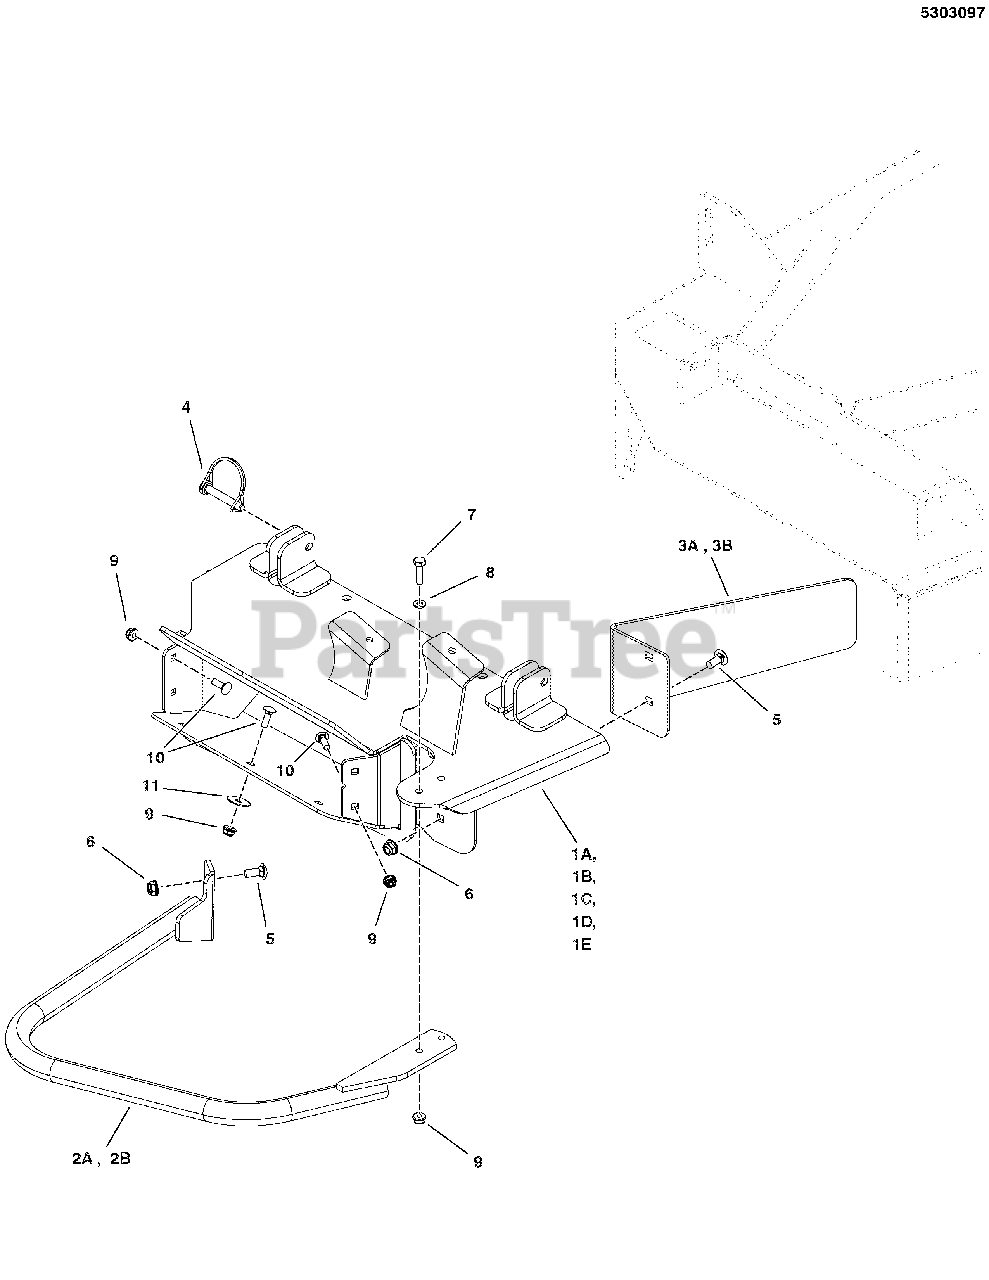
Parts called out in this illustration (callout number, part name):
4	SNAPPERPIN, 5/16 X 2
5	BOLT, 5/16-18 X 3/4, CARRIAGE
6	NUT, 5/16-18 HEX NYLOCK FLANGE
7	BOLT, 1/4-20 X 1" GD5 CZ
8	WASHER, 1/4 SAE
9	NUT, 1/4-20 HEX NYLOCK FLANGE
10	BOLT,1/4-20X0.750,GR5,STD NECK,SQ,ZC/CL
11	WASHER, 1/4 FENDER
